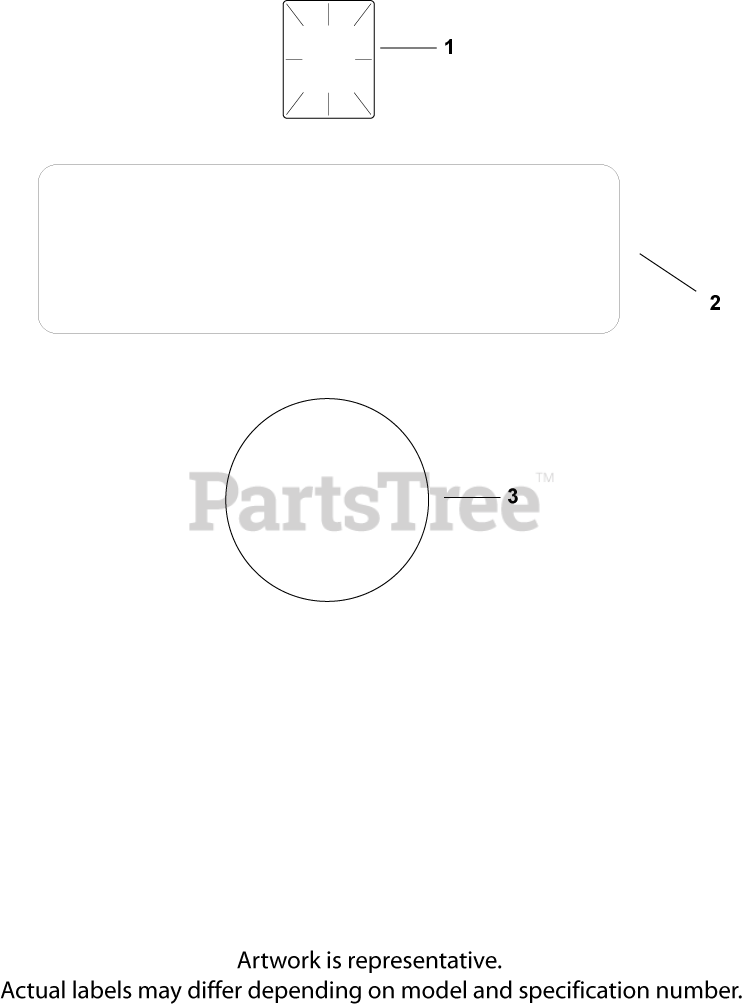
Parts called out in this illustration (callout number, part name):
1	DECAL, CLEAR LAMINATE USE 25 113 70-S
2	DECAL, 25 HP
3	LABEL, (ROUND KOHLER GOLD)-USE 24 113 18
